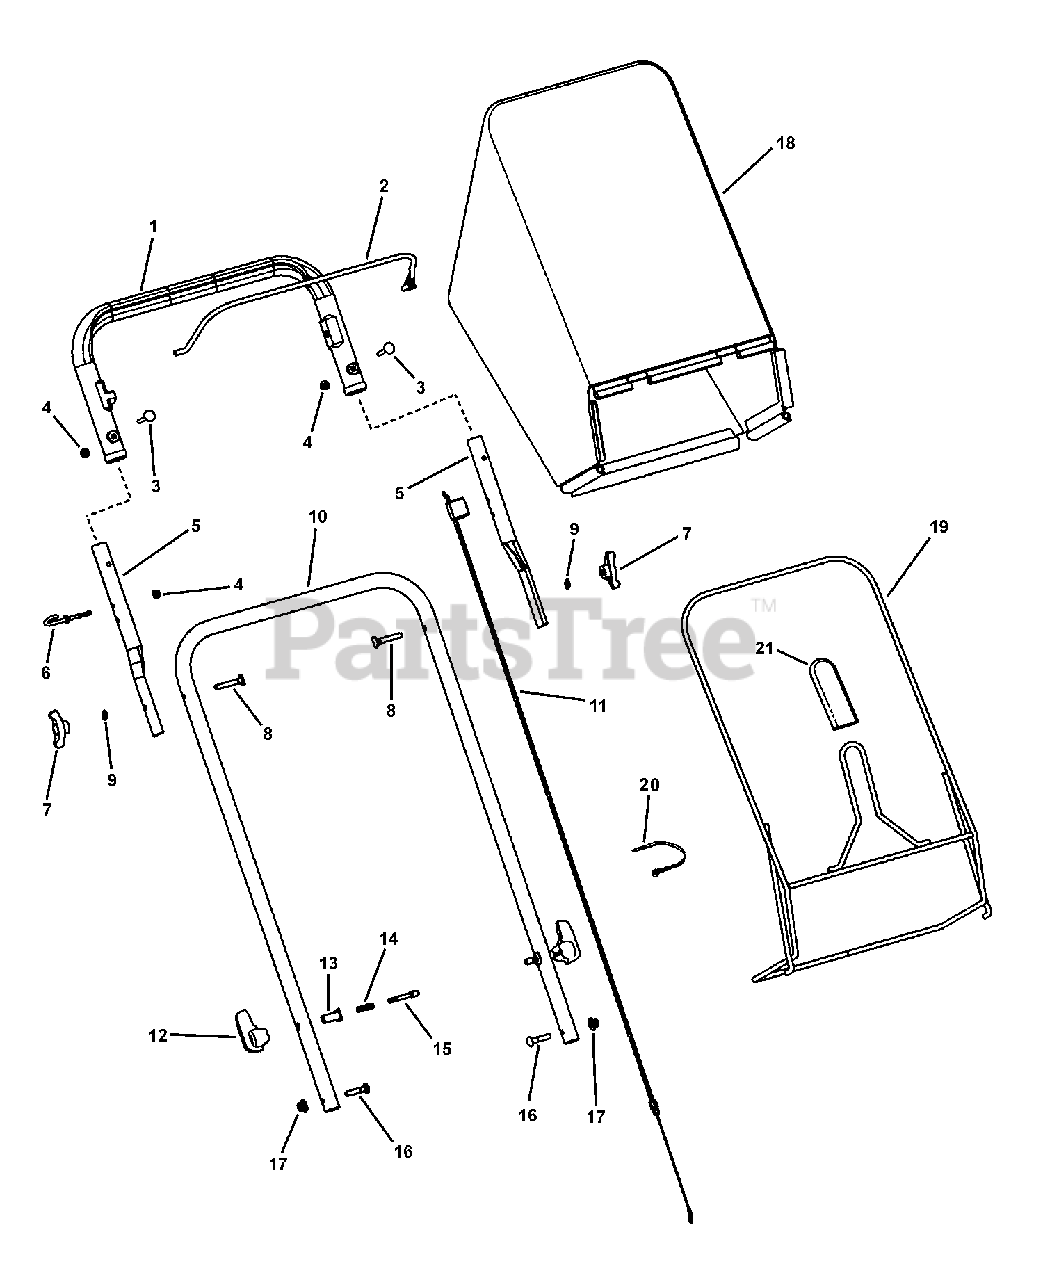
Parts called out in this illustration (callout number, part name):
1	UPPER HANDLE, Plastic, Snapper Push
2	BAIL, Plastic Handle, WBM
3	BOLT, 1/4-20 x 1-3/4" Round Head Square Neck, GR 2, YZ
4	NUT, 1/4-20, Hex Flange (Esna) YZ
5	HANDLE, Connecting, 21"/22" WBM
6	ROPE GUIDE (1/4-20 thread)
7	KNOB, 5/16-18 Wing (5/16-18 thread) (Black)
8	BOLT, 5/16-18 x 2" Curved Head Square Neck, GR 2
9	WASHER, 5/16" Internal Tooth Lock
10	HANDLE, Lower, 22" WBM
11	CABLE, Bail, 22" WBM
12	KNOB, Quick Release
13	BUSHING, Handle Pin
14	SPRING, Compression
15	PIN, Handle Adjust
16	BOLT, 5/16-18 x 1-1/2" Round Head Short Square Neck, GR 5
17	NUT, 5/16-18 Large Flange Center Lock
18	GRASS BAG, 22" Rear Discharge
19	BAG FRAME, 22" WBM (Weldment)
20	WIRE TIE,11" Standard Black Nylon
21	GRIP, Rectangular (Black)
